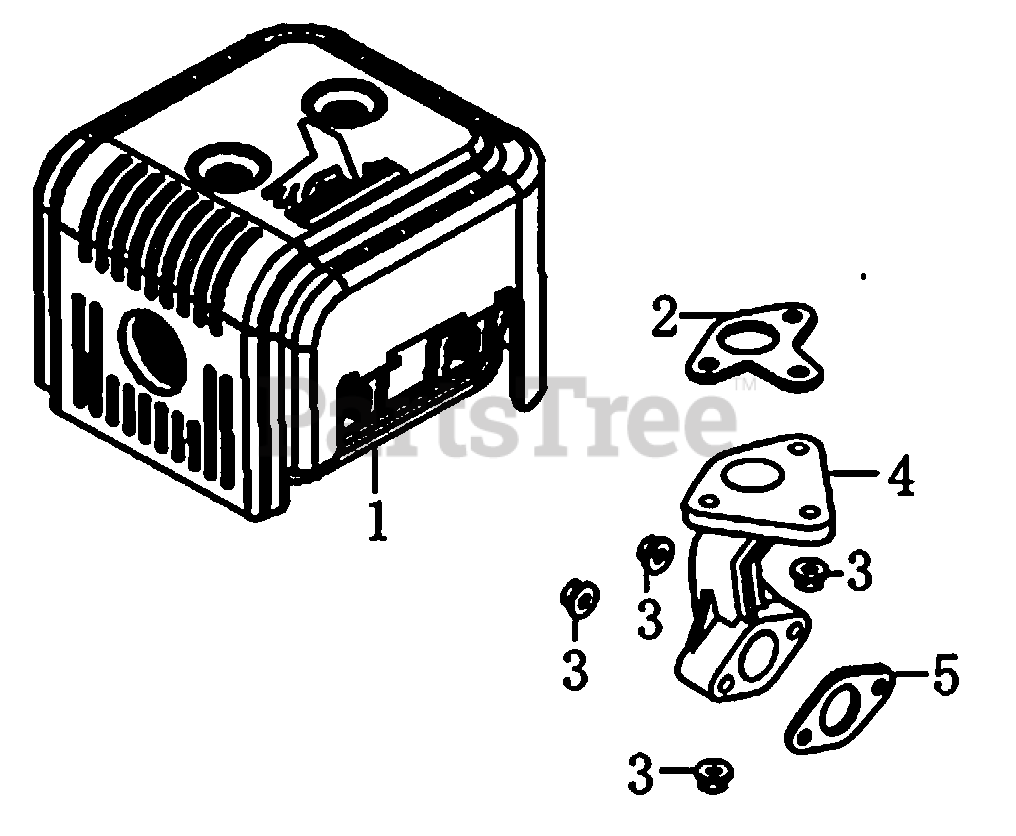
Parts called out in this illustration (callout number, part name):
1	MUFFLER ASSY.
2	GASKET,EX.PIPE
3	NUT , HEX ., M8
4	MANIFOLD, EXHAUST
5	GASKET , MUFFLER
